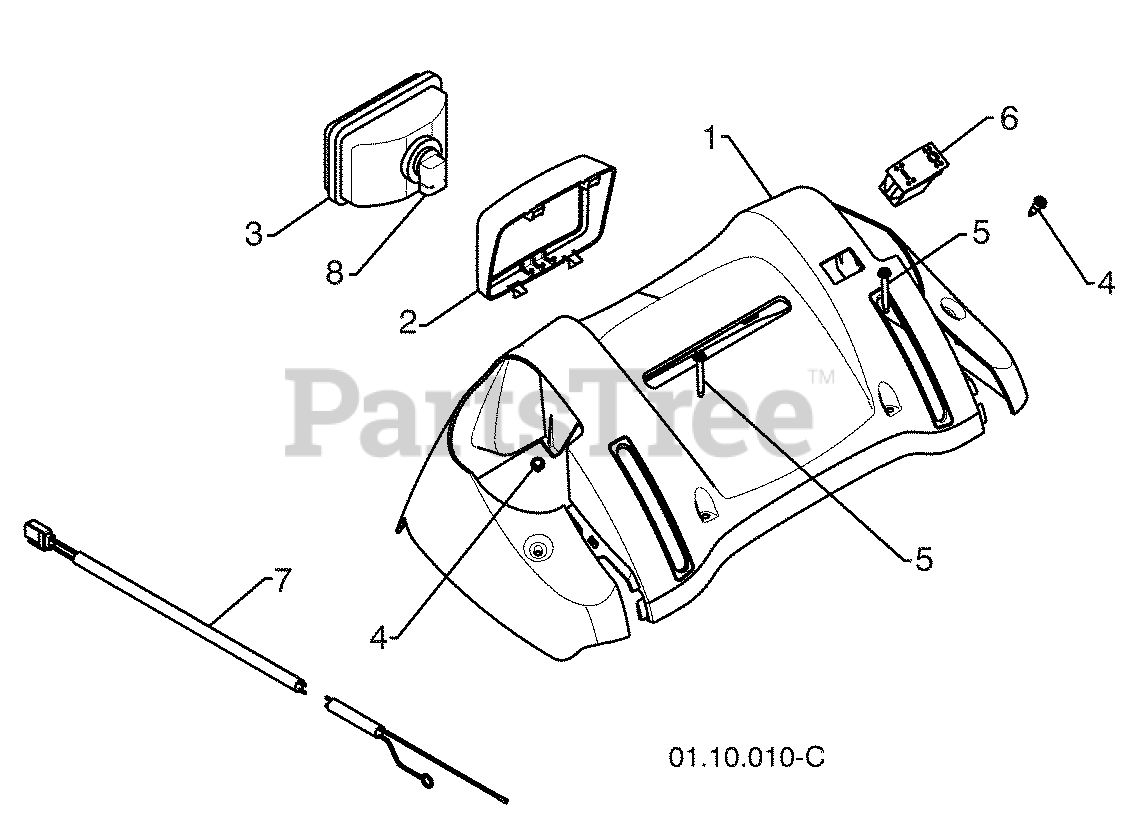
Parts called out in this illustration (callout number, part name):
1	CONSOLE PANEL GRAY
2	HEADLIGHT BEZEL GRAY
3	HALOGEN HEADLIGHT
4	SHOULDER SCREW 10--24 X .625
5	SCREW 10--24 X 1.25
6	GRIP SWITCH
7	WIRE HARNESS
